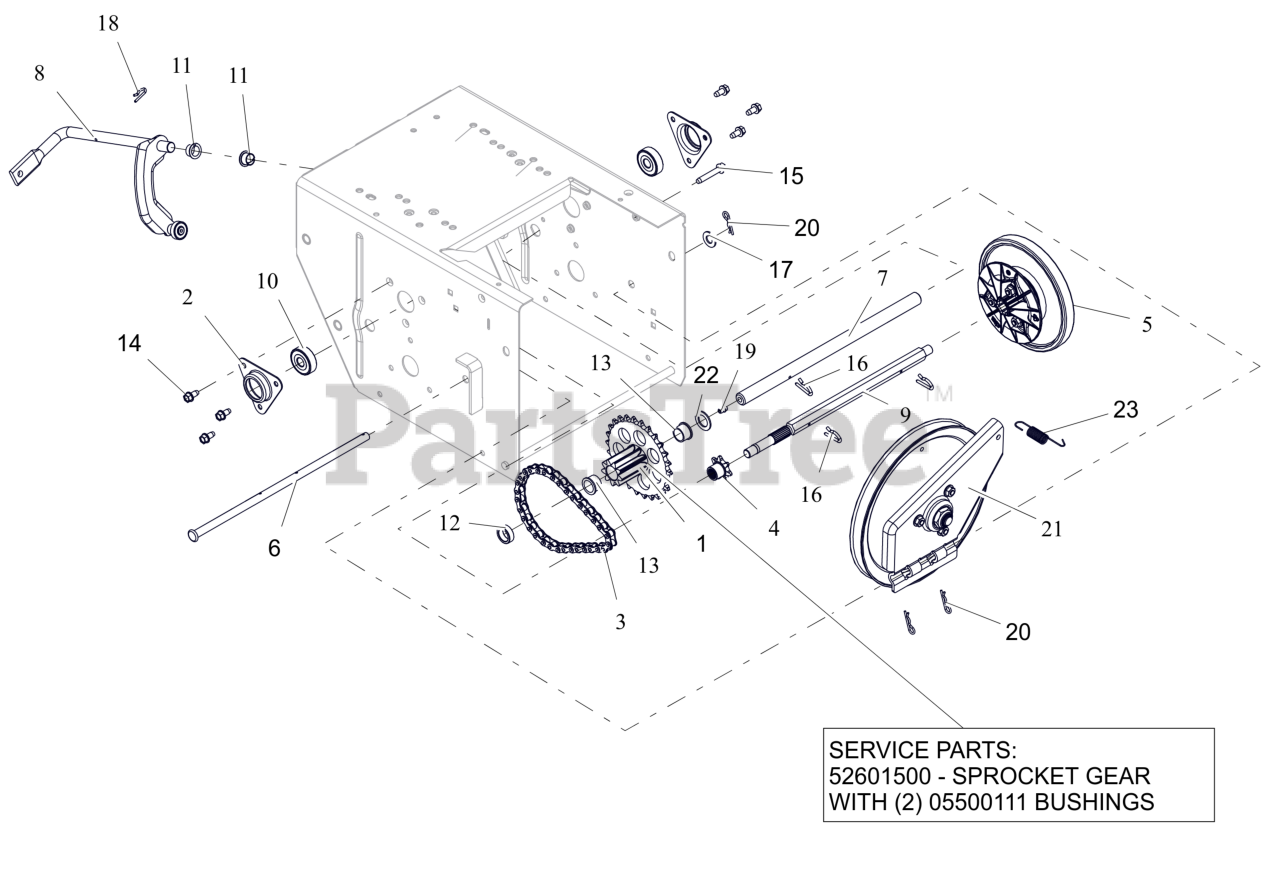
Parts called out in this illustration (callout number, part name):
1	PINION & SPROCKET
1	PINION & SPROCKET W/BUSHINGS
2	FLANGE, BEARING
3	CHAIN - #41, 32 PITCHES
4	SPROCKET, PINION 7T W/SPLINE
5	DISC, FRICTION DRIVE-ASSEMBLY
6	PIN, PIVOT
7	SHAFT, PINION
8	ARM, SHIFT - ASSEMBLY
9	SHAFT, HEX
10	BRG-BALL .437X1.375X.437
11	BUSHING, POLYLINER-.50 SPLIT
12	BSHG-SLV, .635X.880X.305
13	BSHG-FLG .625X.750X.500X.875
14	SCR-TAP .25-20X.50 HWH ZCC
15	SCR,TAP .25-20X1.50 HWH TR ZCC
16	PIN, SPRING CLIP
17	WSHR,FLT .406X.812X.065 ZCC
18	CLIP, SPRING
19	ZERK,FITTING .25X.125 DRIVE IN
20	PIN, HAIR #213 .08X1.19 ZCC
21	PLATE, SWING ASSEMBLY-DEEP
22	WSHR, FLT .630X1.005X.062 ZCC
23	SG-TENS .048X.50X2.8
